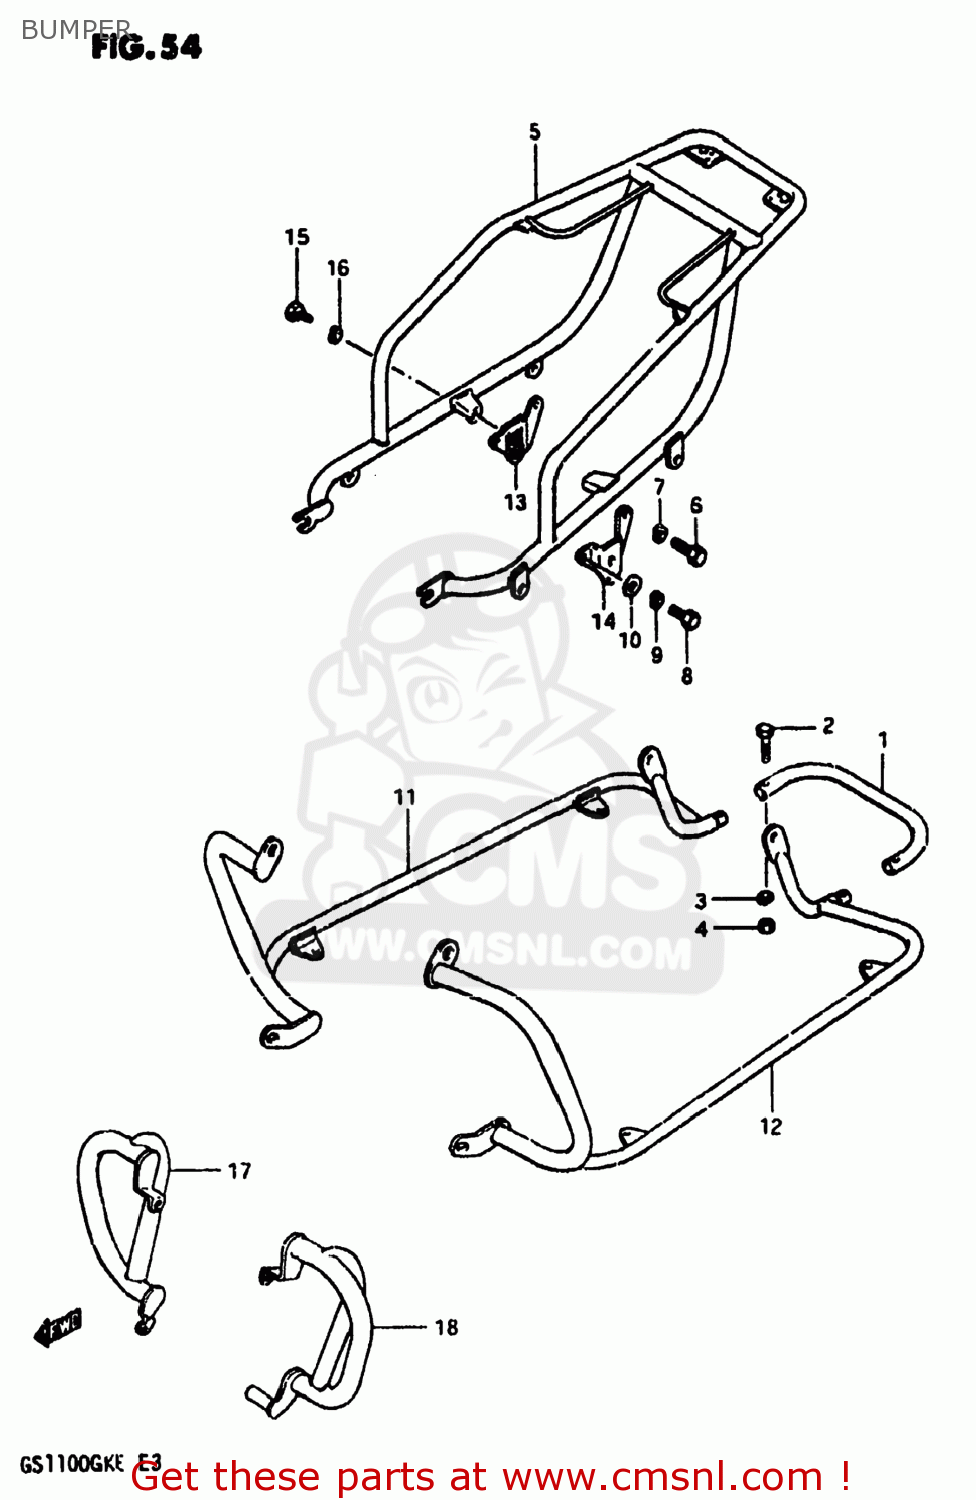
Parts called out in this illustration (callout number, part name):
1	BUMPER,REAR
2	BOLT
3	LOCK WASHER
4	NUT
5	CARRIER TRAVEL TRUNK
6	BOLT
7	LOCK WASHER
8	BOLT
9	LOCK WASHER
10	WASHER
11	CARRIER,REAR SIDE,RIGHT
12	CARRIER,REAR SIDE,LEFT
13	BRKT COMP RR CARR R
14	BRKT COMP RR CARR L
15	BOLT
16	LOCK WASHER
17	COVER COMP,ACCESSORY B
18	ACCESSORY BAR,CASE LEFT
